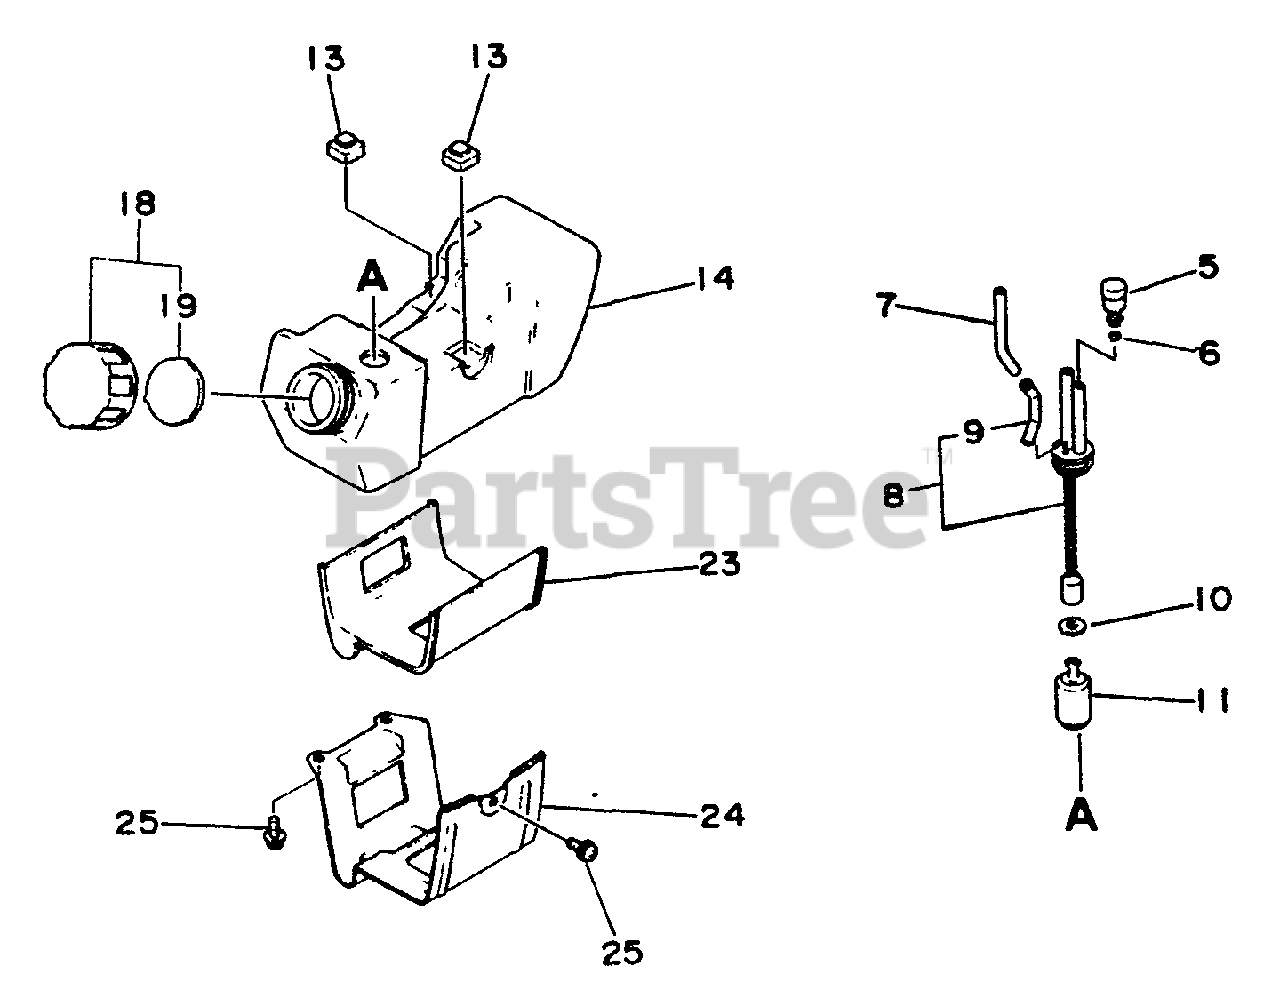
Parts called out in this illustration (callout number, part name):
5	VENT ASSY
7	PIPE, FUEL 3×6×45
8	PIPE, FUEL
9	CONNECTOR, PIPE
10	WASHER 5.5×12×0.8
11	FILTER, FUEL
13	CUSHION
14	TANK, FUEL
18	CAP ASSY
19	GASKET
23	CUSHION
24	GUARD, FUEL TANK
25	SCREW 5×10
